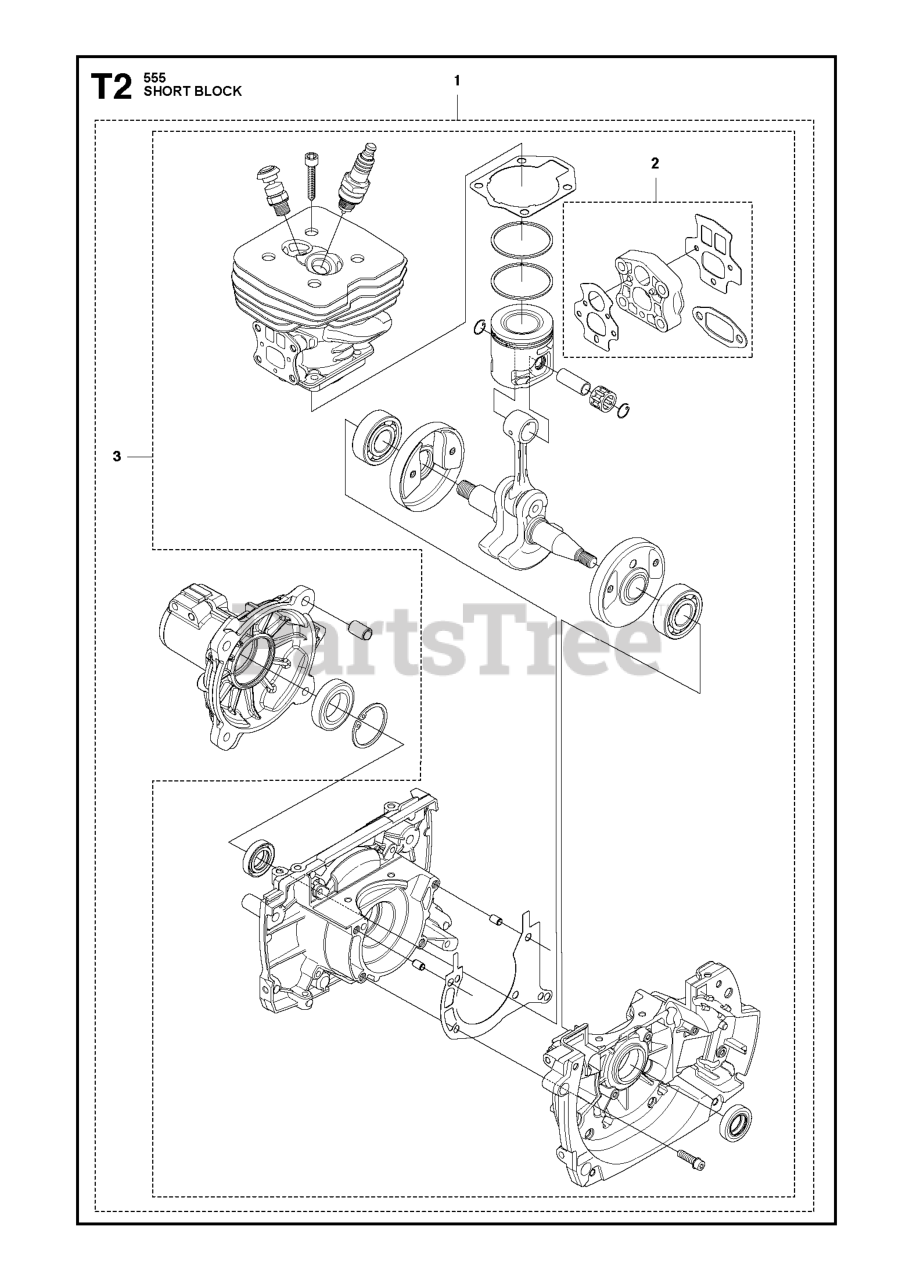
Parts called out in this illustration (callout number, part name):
1	SHORT BLOCK ASSY SPARE PART
2	Crankcases
3	SHORT BLOCK ASSY SPARE PART
